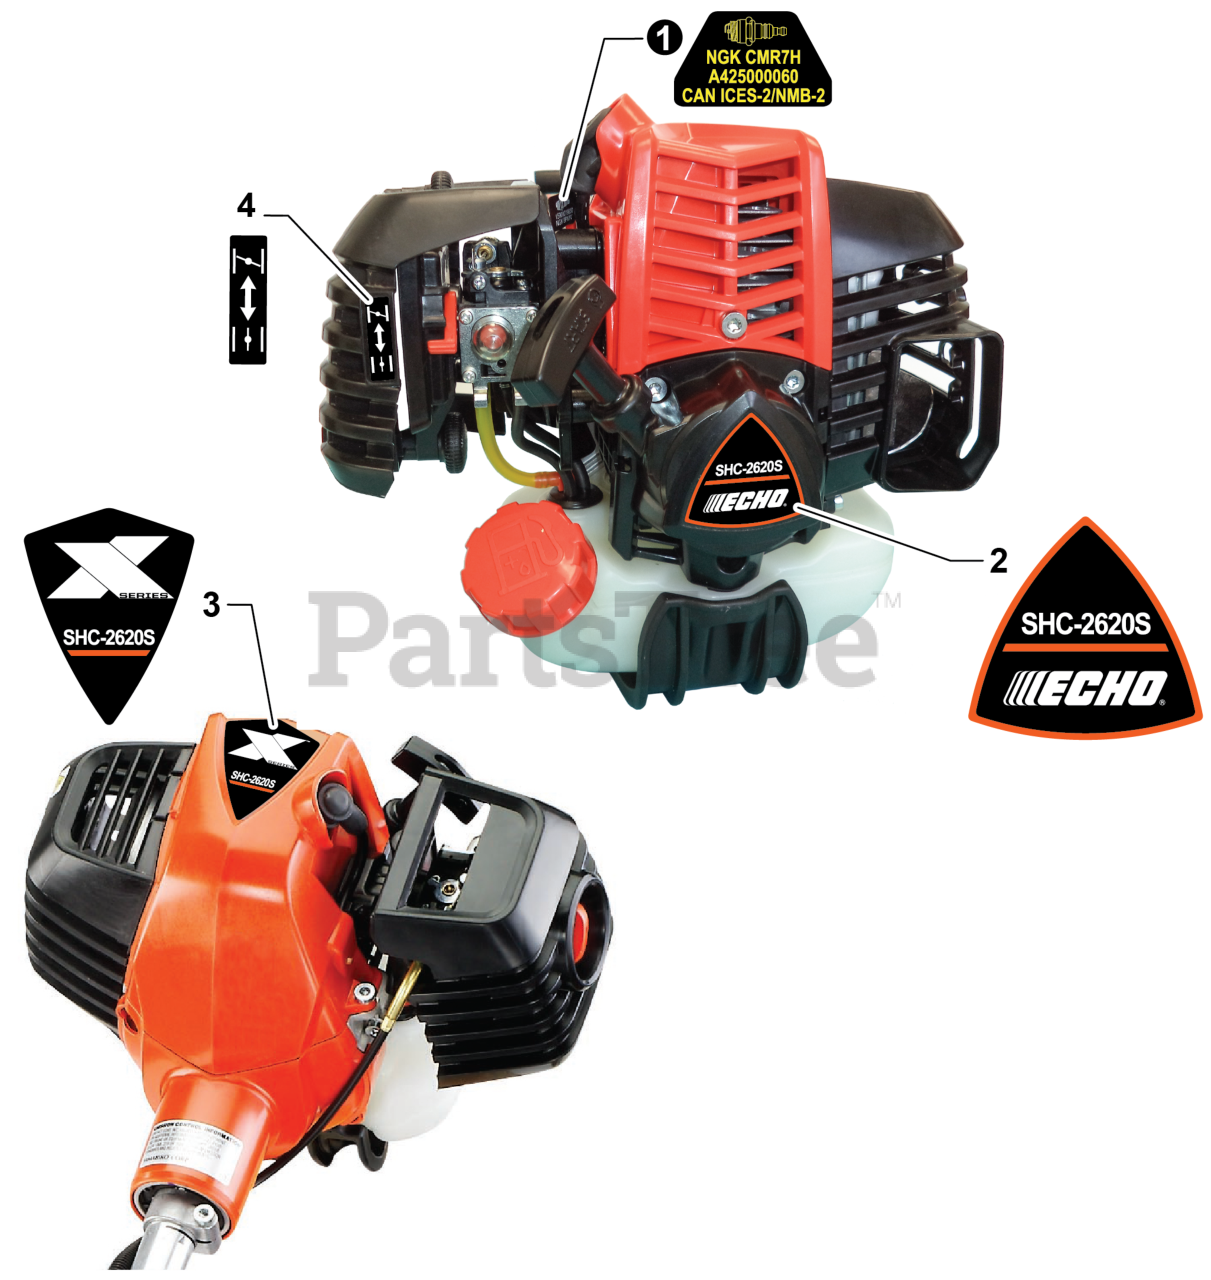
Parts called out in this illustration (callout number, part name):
1	LABEL - SPARK PLUG - CMR7H
2	LABEL - RECOIL STARTER - SHC-2620
3	LABEL - MODEL SHC-2620
4	LABEL - CHOKE
